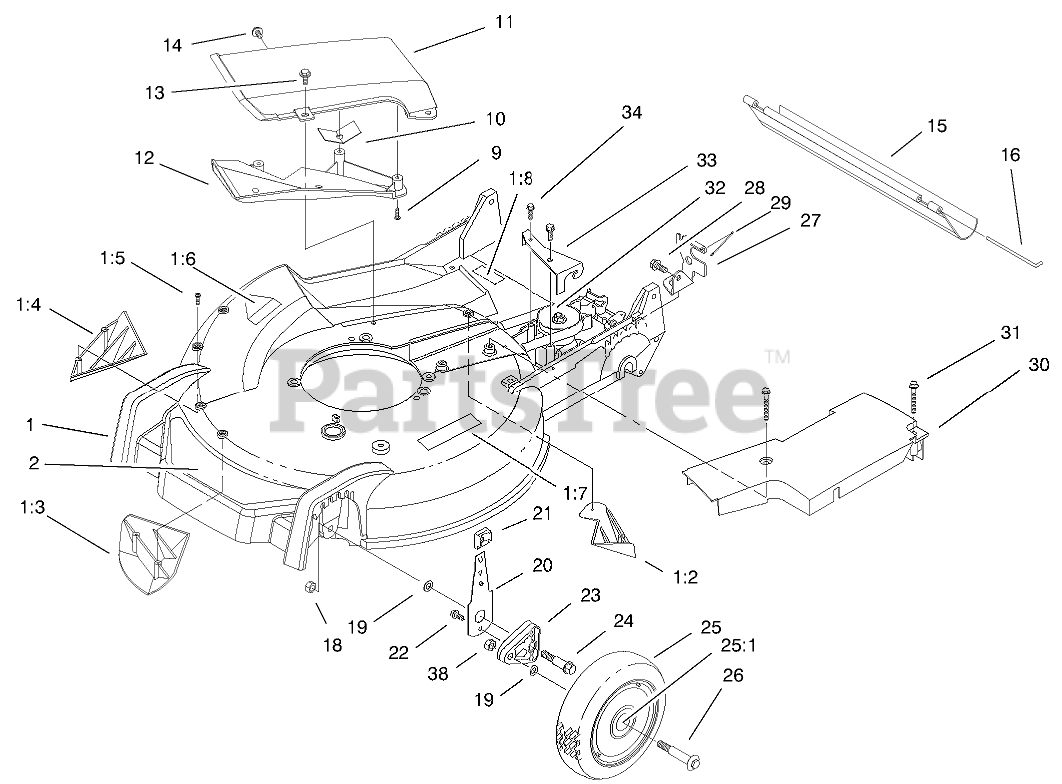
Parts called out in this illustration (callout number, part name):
1	HOUSING
1:2	KICKER-REAR
1:3	KICKER-FRONT
1:4	KICKER-RH
1:5	SCREW-PPH
1:6	DECAL-DANGER
1:7	DECAL-WARNING
1:8	DECAL-WARNING
2	DECAL - DECK
10	Cover Guard
11	COVER-BLACK
12	Deflector
13	SCREW-HWH
14	SCREW AND WASHER ASM
15	SHIELD-TRAILING
16	ROD-SHIELD
18	NUT-LOCK
19	WASHER
20	FRONT SPRING ARM ASM
21	KNOB-ARM
22	SCREW-HWH
23	ARM-PIVOT, FRONT
24	BOLT-SHOULDER
25	WHEEL AND TIRE ASM
25	WHEEL ASM
25:1	BUSHING
26	BOLT-WHEEL
26	BOLT-SHOULDER
27	BRACKET-TRACTION, ADJ.
28	SCREW-HWHTF
29	RETAINER-CABLE
30	BELT COVER ASM
31	SCREW-HHFTF
32	GEARCASE ASM
33	BRACKET-GUIDE, BELT
34	SCREW-HWHTF
38	NUT-LOCK
